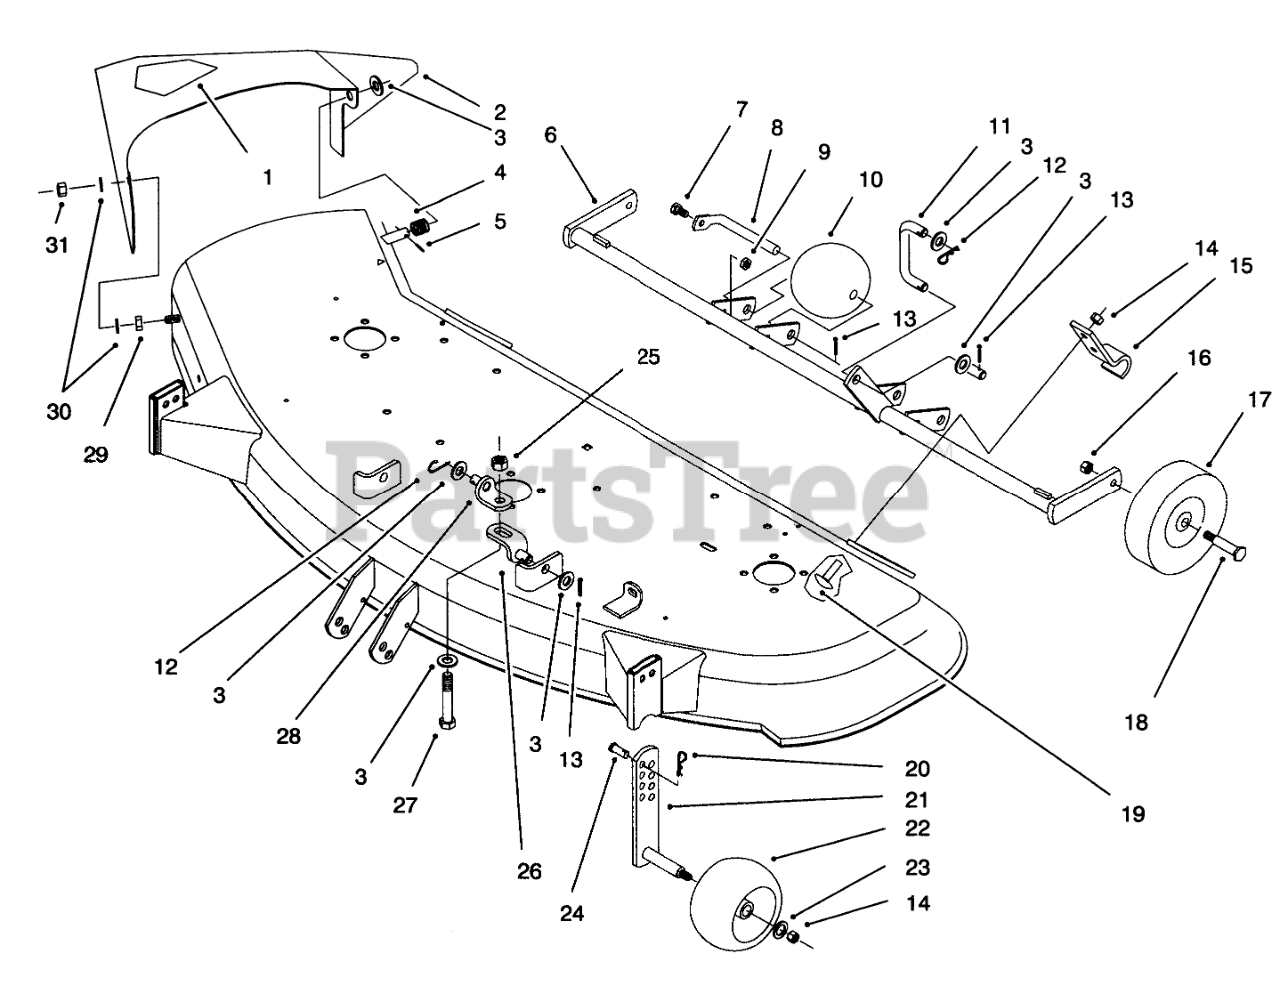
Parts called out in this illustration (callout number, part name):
1	DECAL-DANGER
2	Chute & Decal Assembly (Incl. Ref.# 1)
3	WASHER-FLAT
4	SPRING-DEFLECTOR
5	PIN-COTTER
6	SUPPORT-GAGE WHEEL
7	SCREW-HH
8	SHAFT-ROLLER
9	NUT-LOCK, NI
10	ROLLER
11	LINK-REAR
12	PIN-COTTER, HAIR
13	PIN-COTTER
14	NUT-LOCK, NI
15	Clamp
16	NUT-HEX
17	WHEEL
18	BOLT-SHOULDER
19	BOLT-CARR
20	Hairpin Cotter
21	GAGE-WHEEL
22	WHEEL-GAGE
23	WASHER-FLAT
24	PIN-CLEVIS
25	NUT-JAM
26	BRACKET-LIFT, LOWER
27	SCREW-HH
28	BRACKET-LIFT, UPPER
29	BUSHING-PIVOT
30	WASHER
31	NUT-HJ
